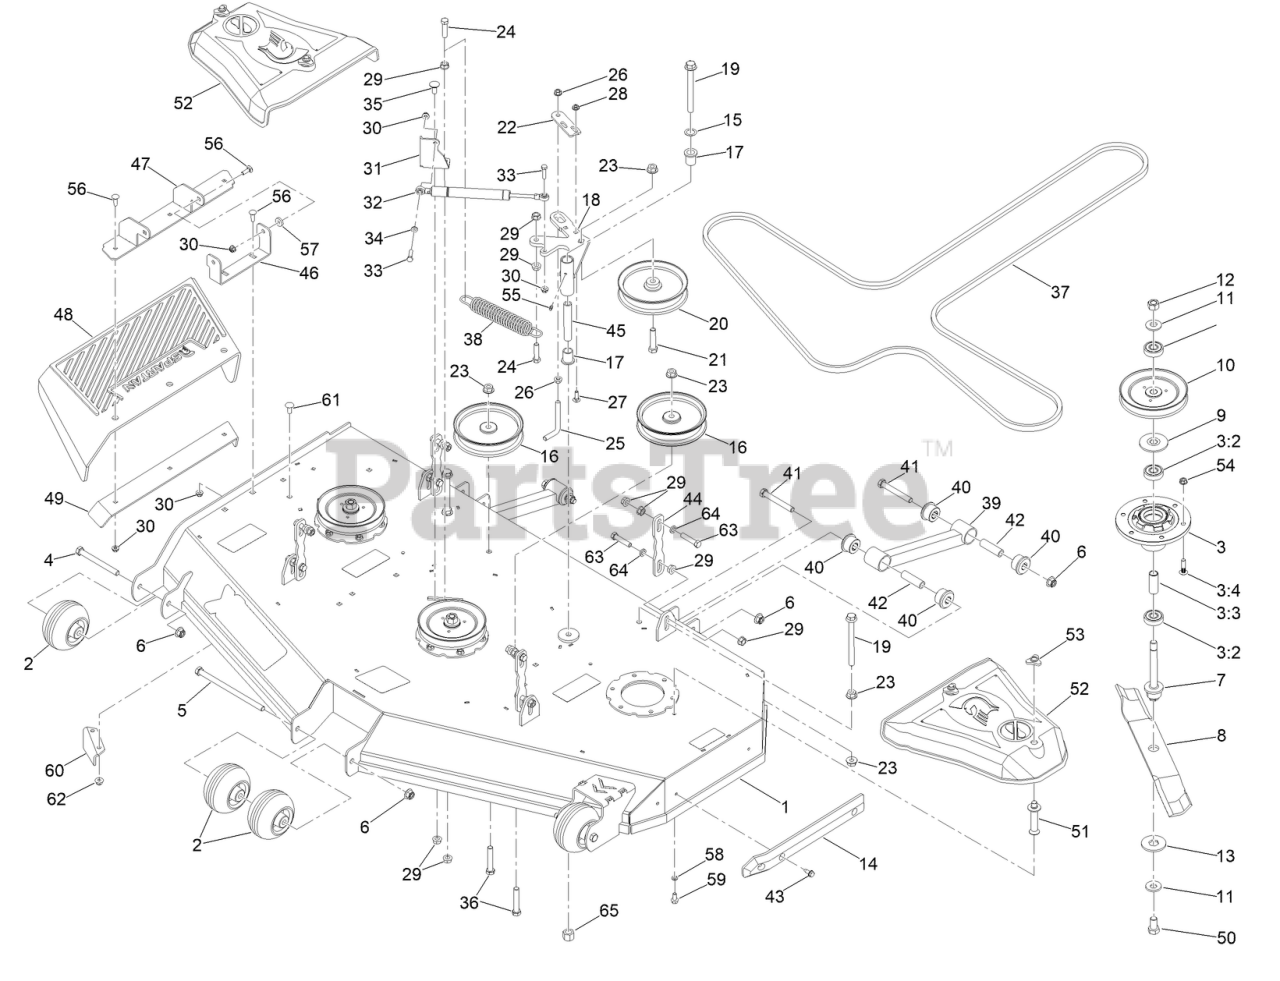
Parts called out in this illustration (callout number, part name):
1	ASM- 60" DECK W/DECALS
2	MWR ANTI-SCALP WHL W/O GREASE FITTING
3	SPINDLE ASM 5IN DECK
3:2	BEARING
3:3	SPACER, BEARING
3:4	BOLT-ROUND HEAD
4	SCREW-HH
5	1/2-13 X 8-1/2 HEX C/S GR 2 ZINC YELLOW
6	NUT-LOCK
7	SHAFT - SPINDLE
8	BLADE-ROTARY
9	GUARD-BEARING TOP 0.673IN
10	PULLEY
11	M16 SPRING WASHER (39MMOD/ 3.9MM THK)
12	M16X1.5 C8.8 HEX NUT
13	WASHER-HEX
14	MWR NYLON DECK GUARD
15	.767IDX1.125ODX.016 THK TRIP WV WASHER
16	6-3/4IN IDLER PULLEY 15/16IN SPACER ASSY
17	3/4IN ID X15/16IN OD X 1-1/8IN FLNG BUSH
18	MWR DECK IDLER PULLEY ARM ASSY PAINT
19	1/2-13 X 5-1/2 HEX FLANGE BOLT GR 8 ZY
20	6-3/4IN IDLER PULLEY 7/16IN SPACER ASM
21	SCREW-HH
22	DECK IDLER PULLEY BELT RETNR BRKT PAINT
23	NUT-HHF
24	SCREW-HH
25	BOLT-L
26	3/8-16 HEX FLANGE NUT W/SERR ZINC YELLOW
27	BOLT-CARR
29	NUT-HF
30	NUT-HF, NI
31	DECK BELT IDLER DAMPER MTG BRKT PAINTED
32	IDLER GAS SPRING
33	SCREW-HH
34	.312IDX.625ODX.062 THK THRUST BRG OI BRZ
35	SCREW-CARR
36	1/2-13 X 2-3/4 HEX FLANGE BOLT (GR.8) YZ
37	BELT-V
38	MWR DECK SPRING
39	RZ MWR DECK STABLZR ASSY
40	RED A80 SUSP BUSHING
41	1/2-13 X 3-3/4 HEX C/S (GR.5) ZC/YEL
42	UTV A-ARM BUSHING SLEEVE
43	SCREW-HWH, THREAD CUT
44	HANGER-DECK PAINTED GREY
45	MWR INNER IDLER SPACER
46	BRACKET-CHUTE
47	DECK CHUTE HINGE ASM
48	RZ MWR RUBBER DISCHARGE CHUTE
49	MWR DECK CHUTE HINGE BACKER BRKT
50	M16X1.5-30MM C10.9 HEX BOLT
51	PIN-BELT COVER
52	COVER-BELT
53	NUT-KNOB
55	1/4IN DRIVE TYPE GREASE FITTING YZ
56	5/16-18 X 1 CARRIAGE BOLT GR 8 YZ
57	.312 ID X .875OD X .1875 THK F/W NYL
58	WASHER-LOCK
59	SCREW-HHF
60	BAFFLE-DISCHARGE
61	SCREW-CARR
62	NUT-HF, NI
63	SCREW-HH
64	.443 ID X .749 OD X .125 THK NYLON BLACK
65	NUT-LOCK, NI
